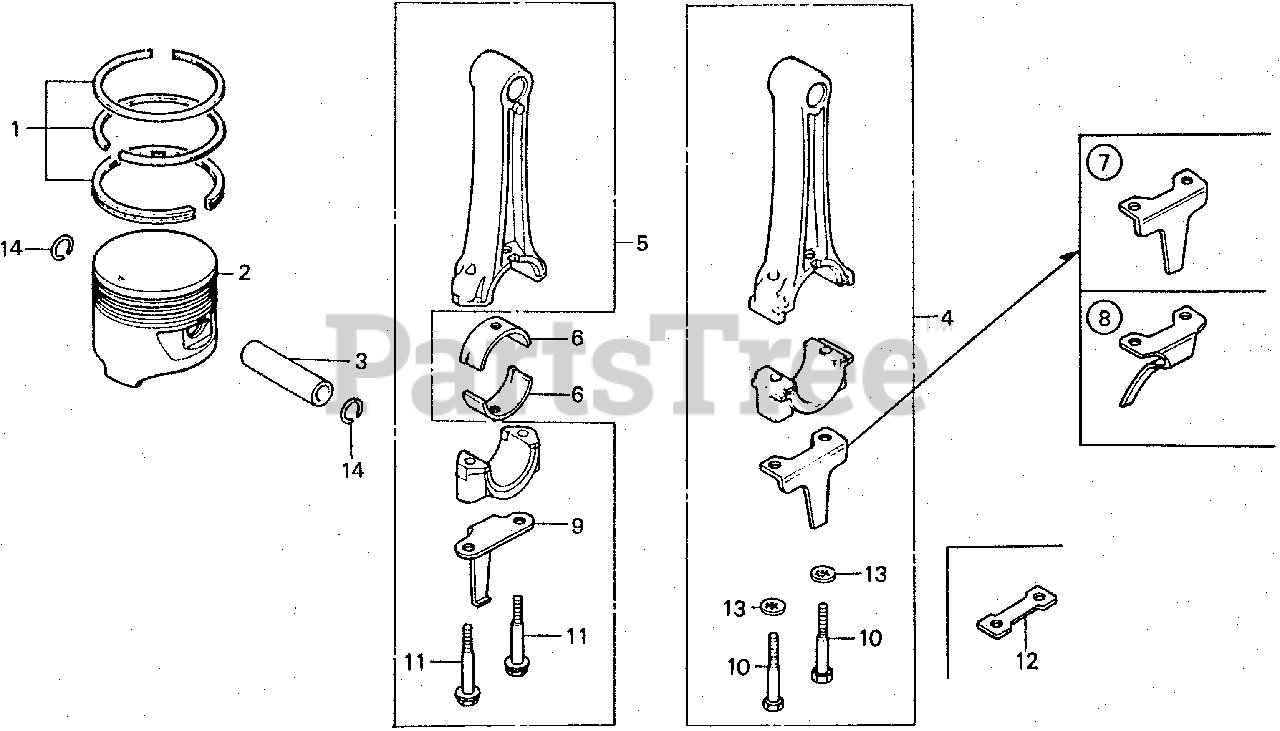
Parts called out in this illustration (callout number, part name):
1	RING SET, PISTON (STD)
1	RING SET, PISTON (STD) (NOT AVAILABLE)
1	RING SET, PISTON (OS 0.25)
1	RING, PISTON (OS 0.50)
1	RING SET, PISTON (OS 0.50)
1	RING SET, PISTON (OS 0.75)
2	PISTON (STD)
2	PISTON (OS 0.25)
2	PISTON (OS 0.50)
2	PISTON (OS 0.75)
3	PIN, PISTON
5	ROD ASSY., CONNECTING
6	BEARING A, CONNECTING ROD (BLACK)
6	BEARING B, CONNECTING ROD (BROWN)
6	BEARING C, CONNECTING ROD (GREEN)
6	BEARING D, CONNECTING ROD (YELLOW)
6	BEARING E, CONNECTING ROD (PINK)
9	DIPPER, CONNECTING ROD
11	BOLT, CONNECTING ROD (8MM)
14	CLIP, PISTON PIN (19MM)
